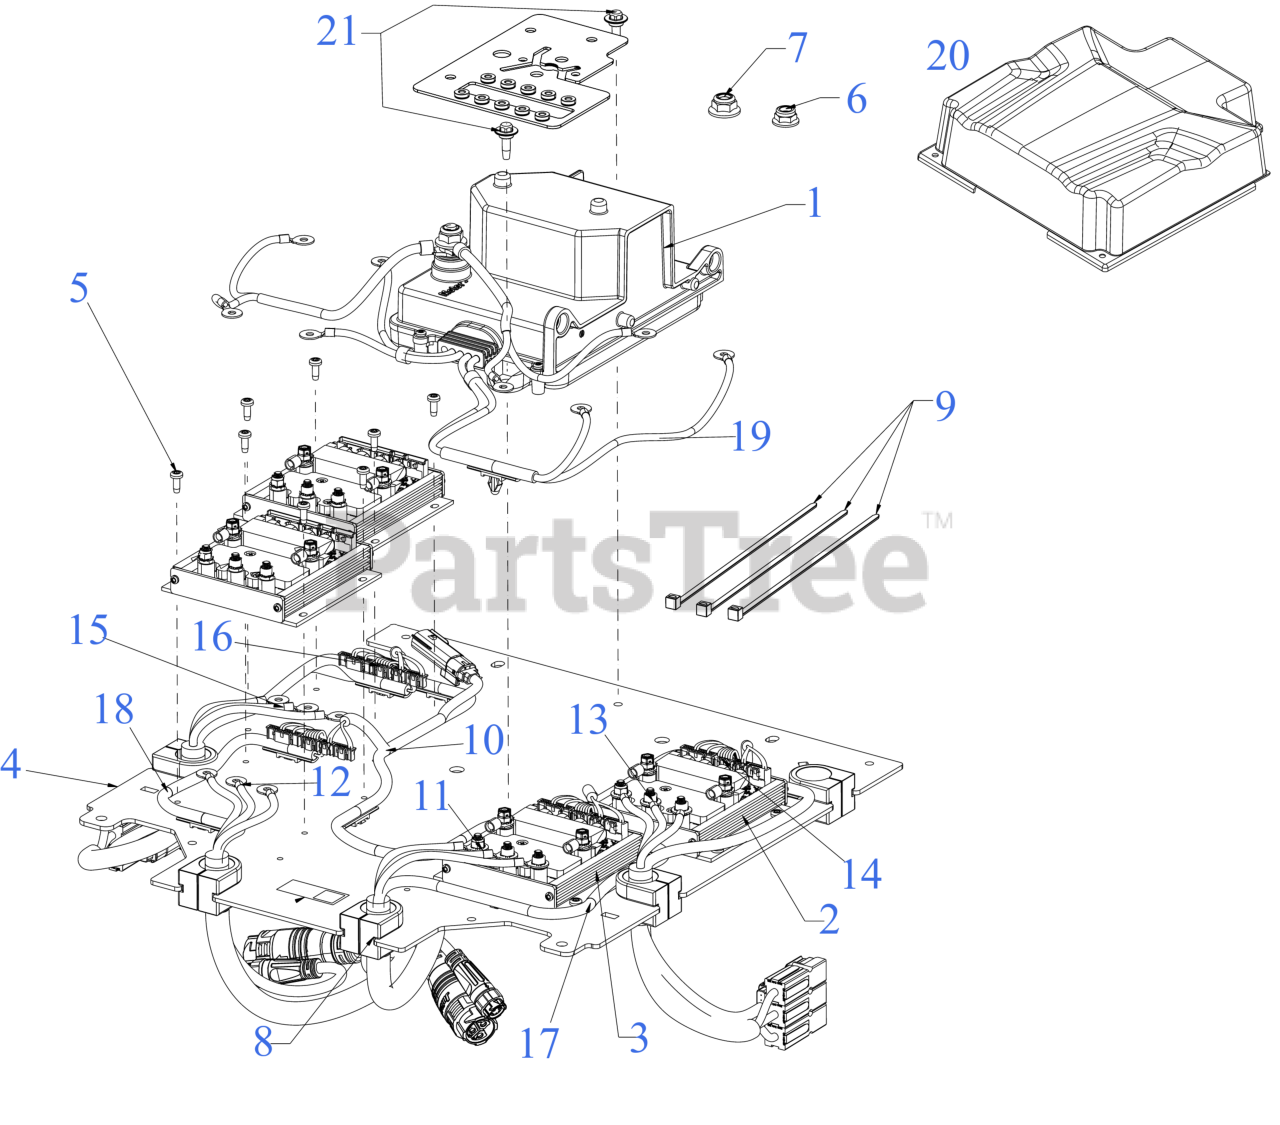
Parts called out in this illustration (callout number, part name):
1	PDM HOUSING (4FUSE)
2	MOTOR CONTROLLER (TRACT)
3	MOTOR CONTROLLER (DECK)
5	SCREW 8-32X.437
6	FLANGE LOCK NUT 5/16-18
7	NUT
9	7" CABLE TIE
10	HARNESS (CAN/CTRL)
11	HARNESS (L/DECK/PH)
12	HARNESS (R/DECK/PH)
13	HARNESS (L/TRAC/PH)
14	HARNESS (L/TRAC/SEN)
15	HARNESS (R/TRAC/PH)
16	HARNESS (R/TRAC/SEN)
17	HARNESS (L/DECK/SEN)
18	HARNESS (R/DECK/SEN)
19	HARNESS (BAT/CP/PDM)
21	SHOULDER SCREW M6-1 .368 X.115
